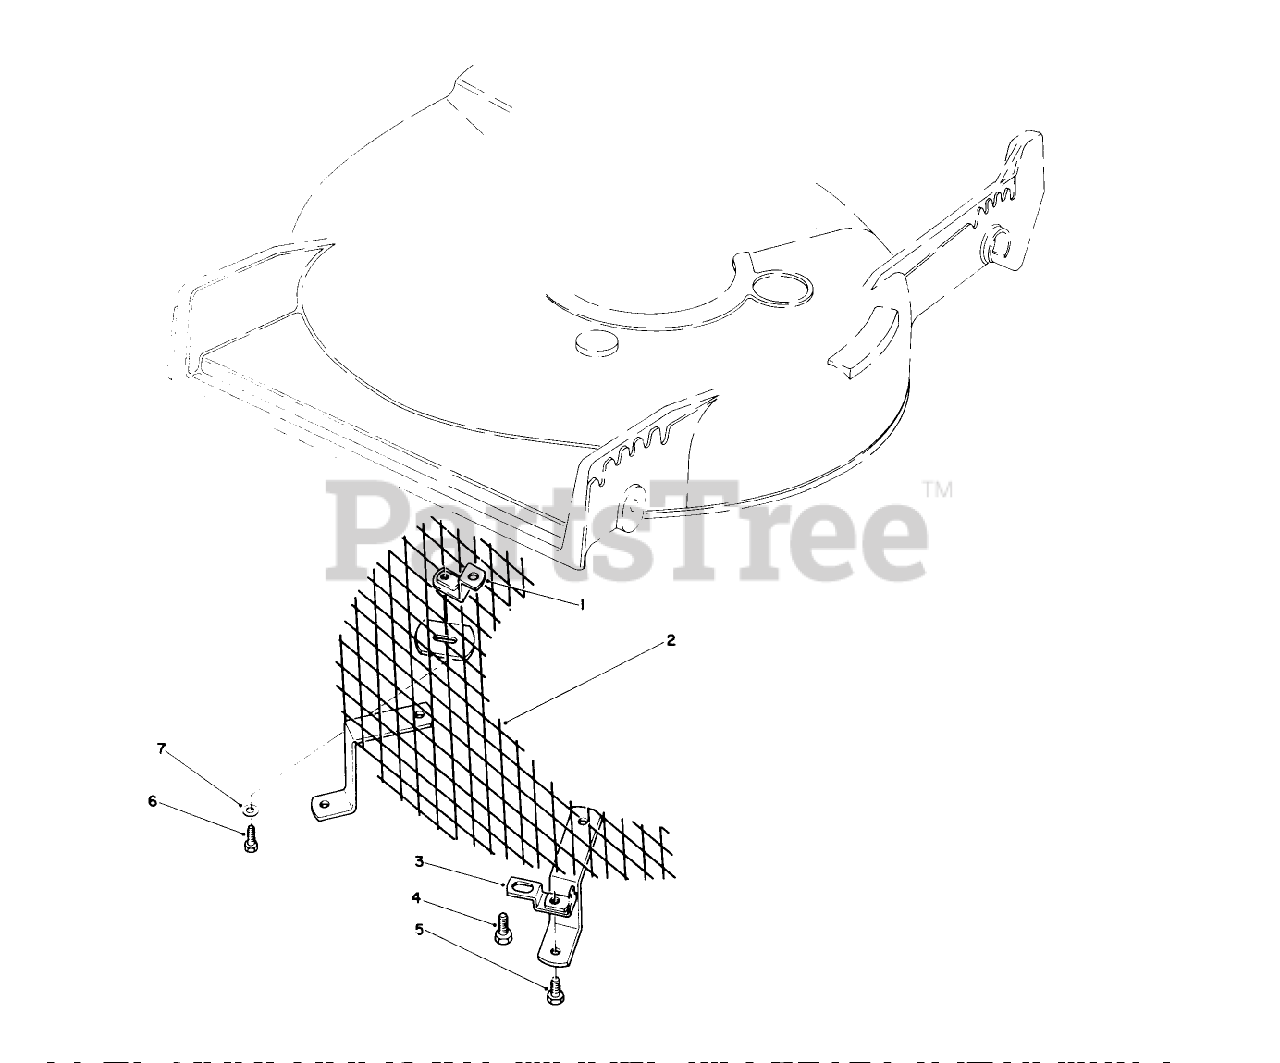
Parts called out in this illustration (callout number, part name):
1	BRACKET WA
3	MTG. BRACKET W.A.
4	SCREW-THD ROLL, HWH
5	SCREW-HH
6	SCREW-HH
7	WASHER-FLAT
